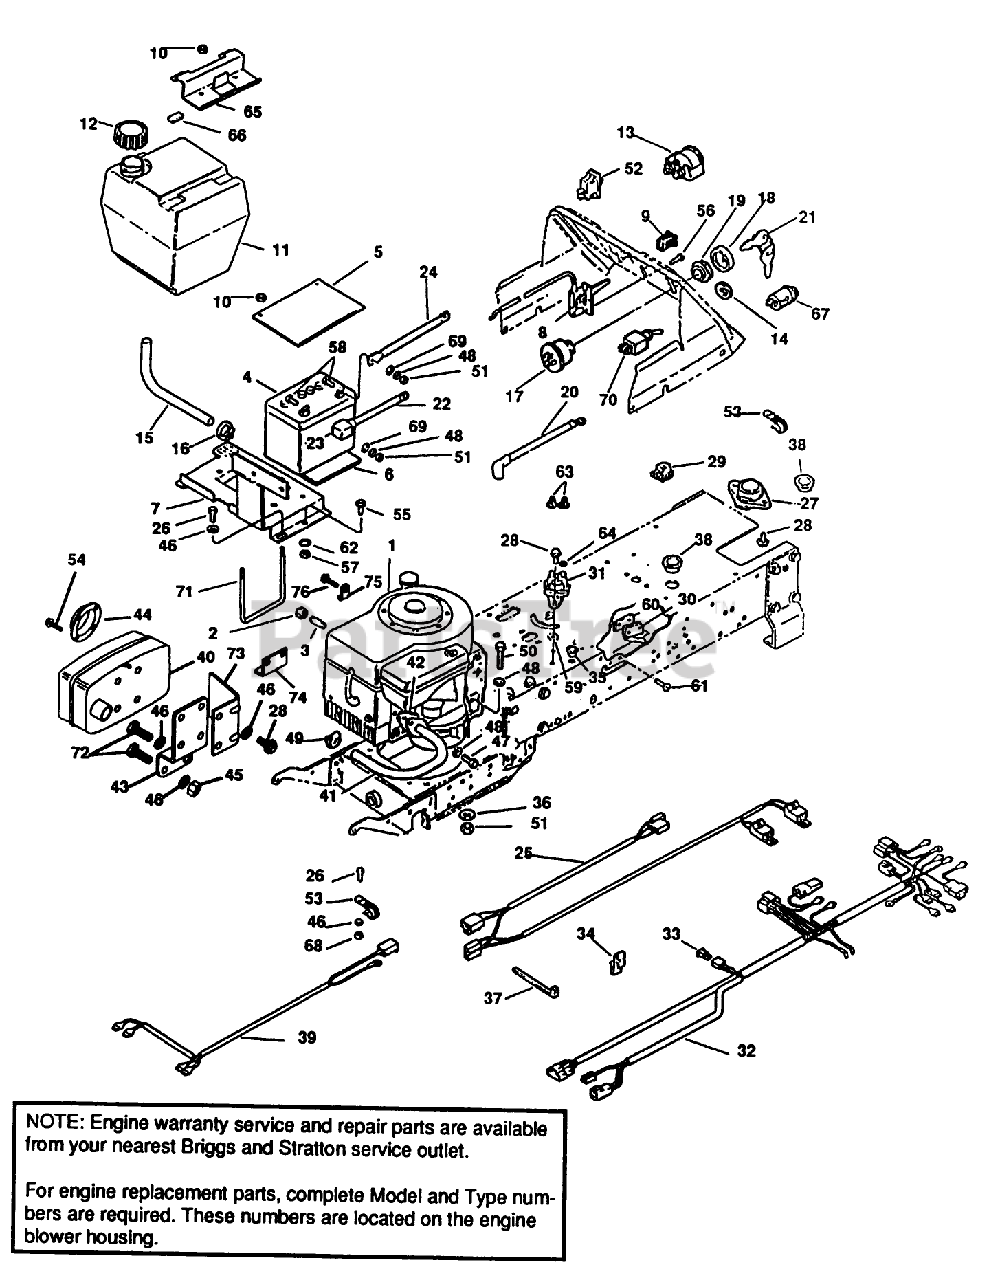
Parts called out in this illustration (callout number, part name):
9	THROTTLE KNOB
10	NUT-LOCK, CONE
11	FUEL TANK ASSEMBLY
12	CAP AY - FUEL M
18	BEZEL
19	NUT
21	KEY
22	CABLE ASSEMBLY
27	SWITCH,SEAT
29	SWITCH
30	SWITCH-SEALED
31	SOLENOID
40	ORDER BRIGGS #493963
42	GASKET
43	BRACKET-EXHAUST
45	NUT
51	NUT SS
52	SWITCH ASSEMBLY
58	SCREW - HEX
64	NUT-HEX
67	LIGHT-PTO INDICTOR
68	NUT
70	SWITCH-PTO W/SAFTY
